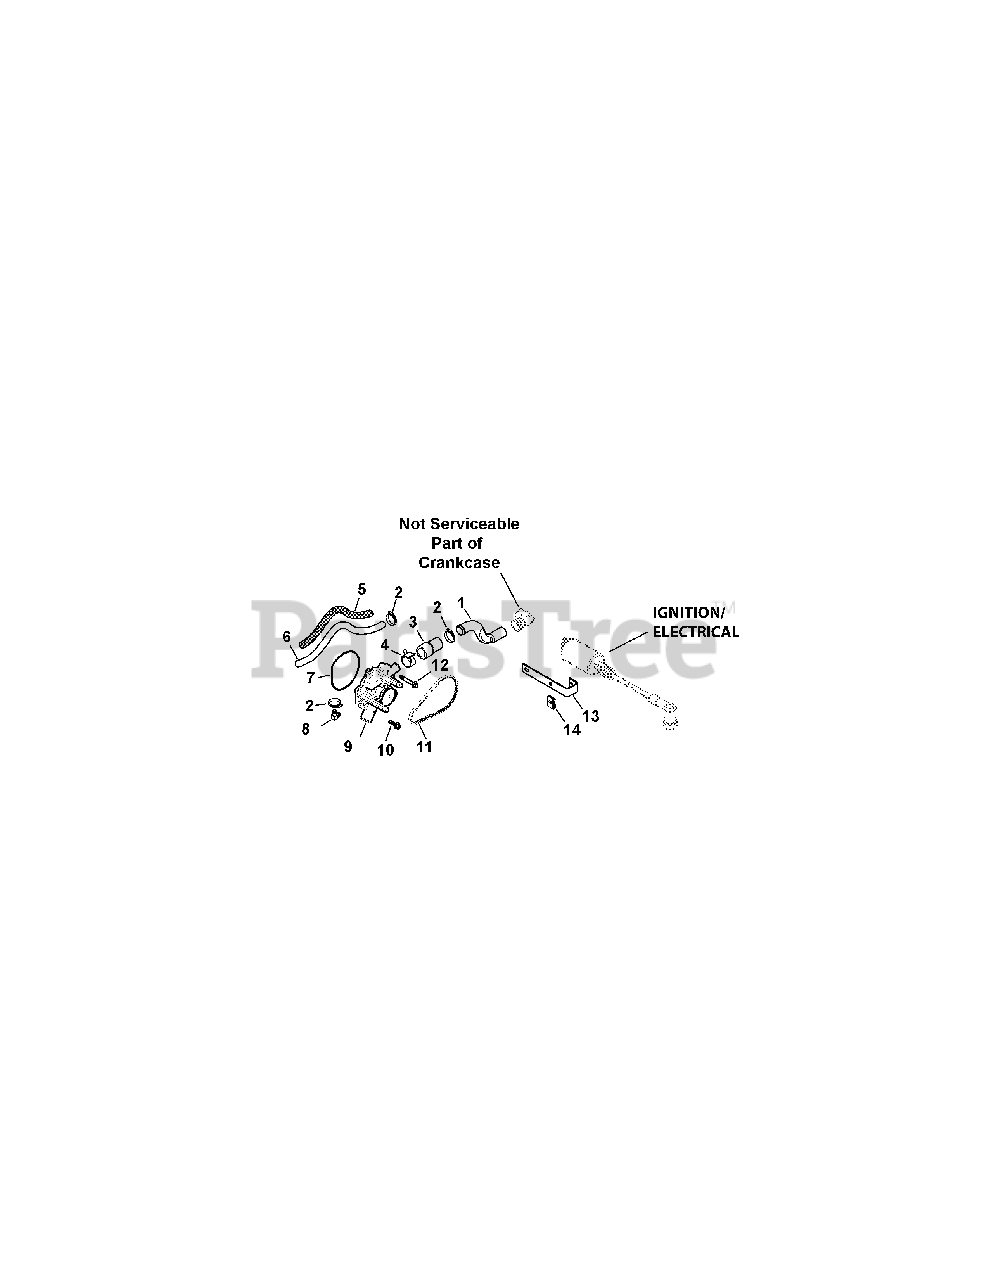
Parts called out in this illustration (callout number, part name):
1	Tube, Crossover
3	Tube, Crossover
5	Sleeve, Insulating 14"
6	Hose, By-pass
10	Screw, Flg, M6 x 1.0 x 20
11	Belt, Water Pump
12	Screw, Flg, M6 x 1.0 x 40
13	Bracket, Ignition Coil (EFI)
14	Clip
